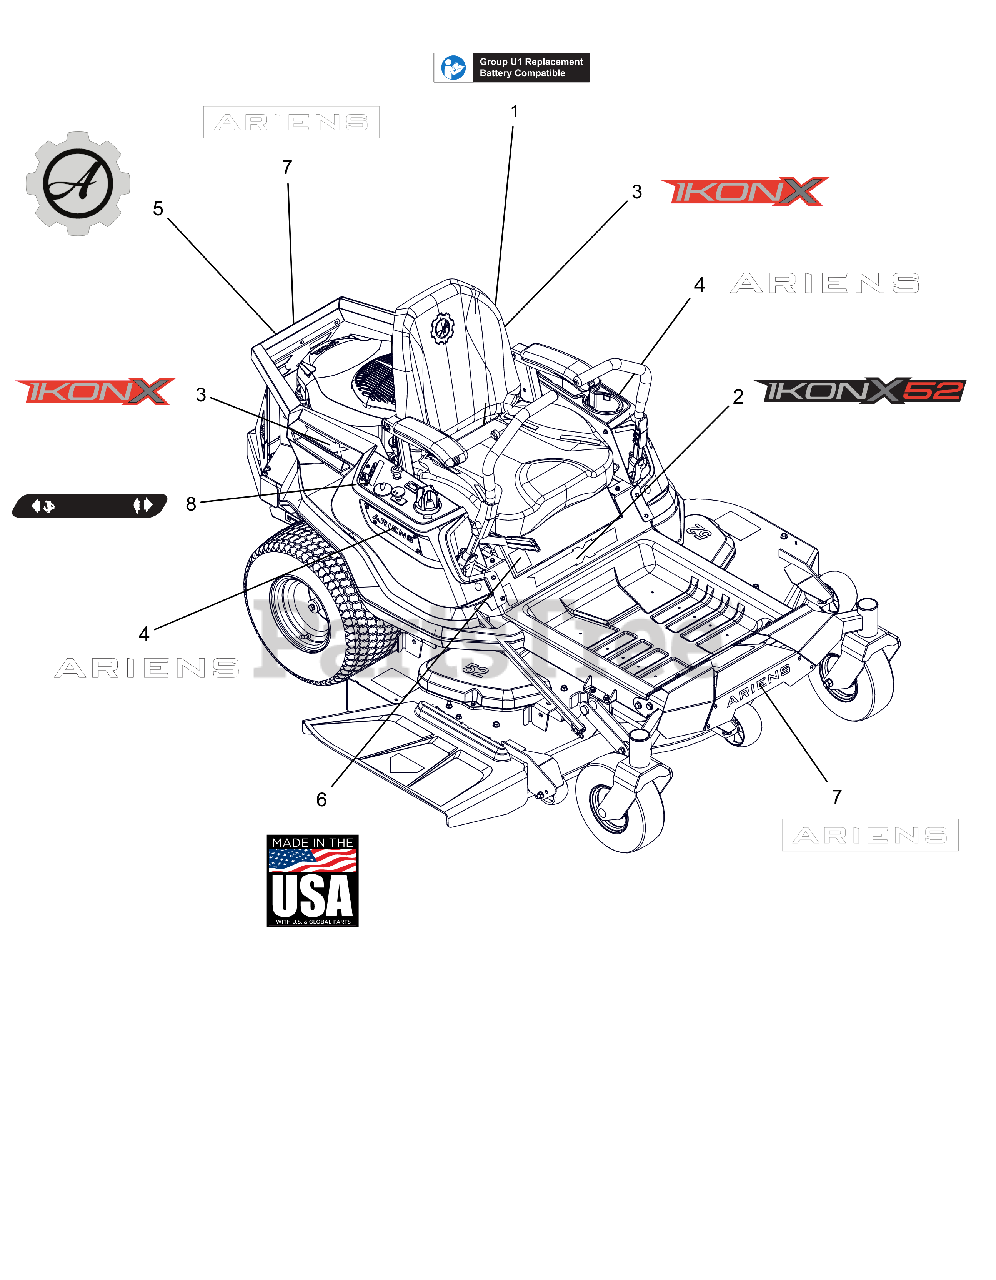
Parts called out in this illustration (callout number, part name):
1	DECAL, U1 BATTERY REPLACEMENT
2	DECAL, IKON-X 52"
3	DECAL, IKON
4	DECAL, ARIENS (6.50")
5	DECAL, ARIENS-GEAR BADGE
6	DECAL, MADE IN USA
7	DECAL - ARIENS 9.625"
8	DECAL, DASH DECAL
